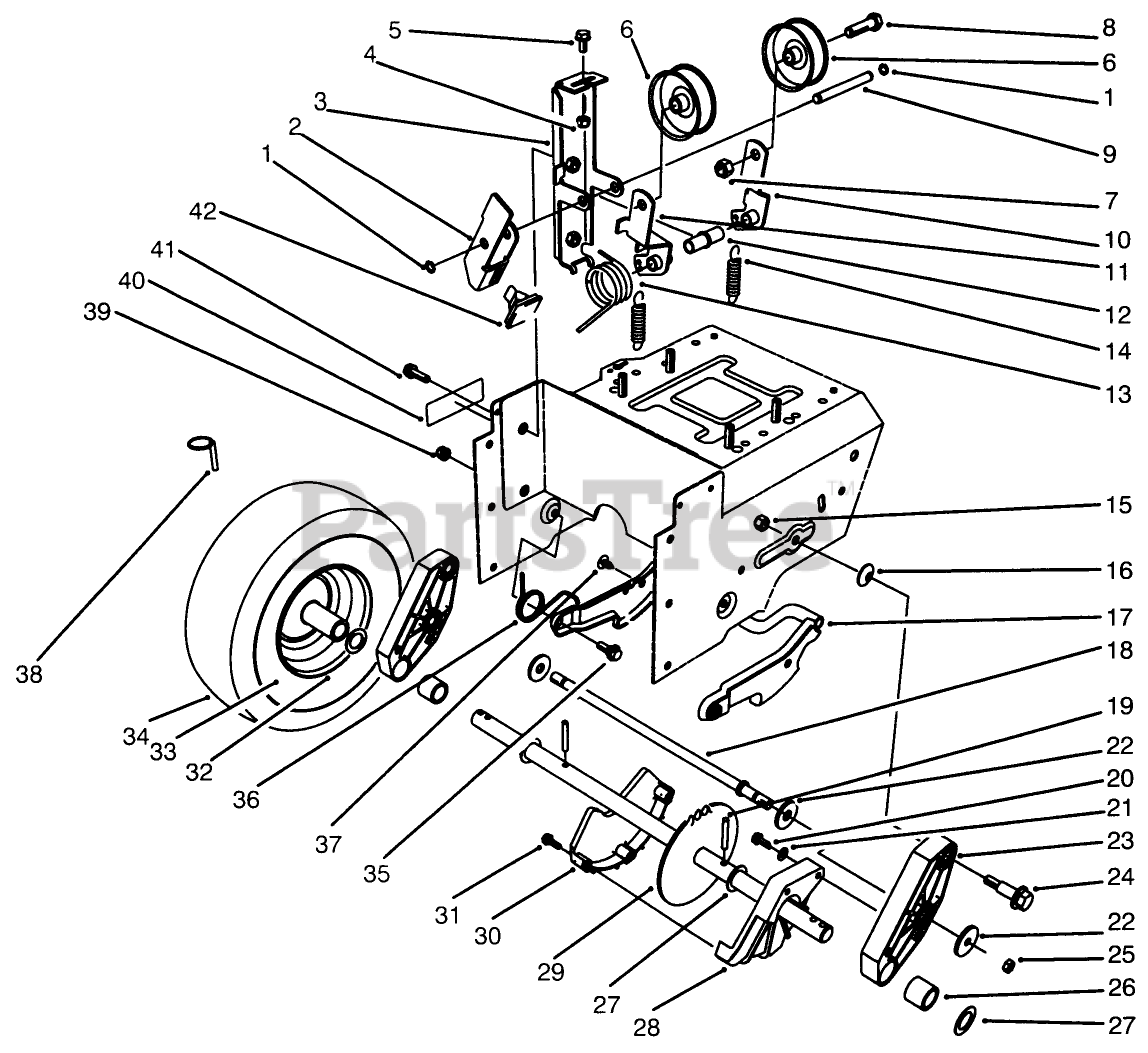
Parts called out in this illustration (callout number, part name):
1	Ring-Retaining
2	ARM-BRAKE
4	NUT-LOCK, NI
5	SCREW-HHF
6	PULLEY-IDLER
8	SCREW-HH
9	PIN-IDLER
10	TRACTION IDLER ARM ASM
12	WASHER-FLAT
14	SPRING-EXTENSION
15	NUT-LOCK, NI
16	WASHER-SPRING
18	ROD-LATCH
19	PIN-ROLL, SLOTTED
20	SCREW-HWH
21	WASHER-FLAT
22	WASHER-SUPPORT
23	PIVOT ARM ASM
24	BOLT-SHOULDER
25	NUT-LOCK, NI
26	BUSHING-AXLE
27	WASHER-THRUST
32	WHEEL
33	TUBE-INNER
35	SCREW-SHOULDER
36	SPRING-LATCH, TORSION
37	FASTENER-PANEL
38	PIN-LYNCH
39	NUT-LOCK, NI
40	DECAL-WARNING
41	SCREW-HHF
42	PAD-BRAKE
